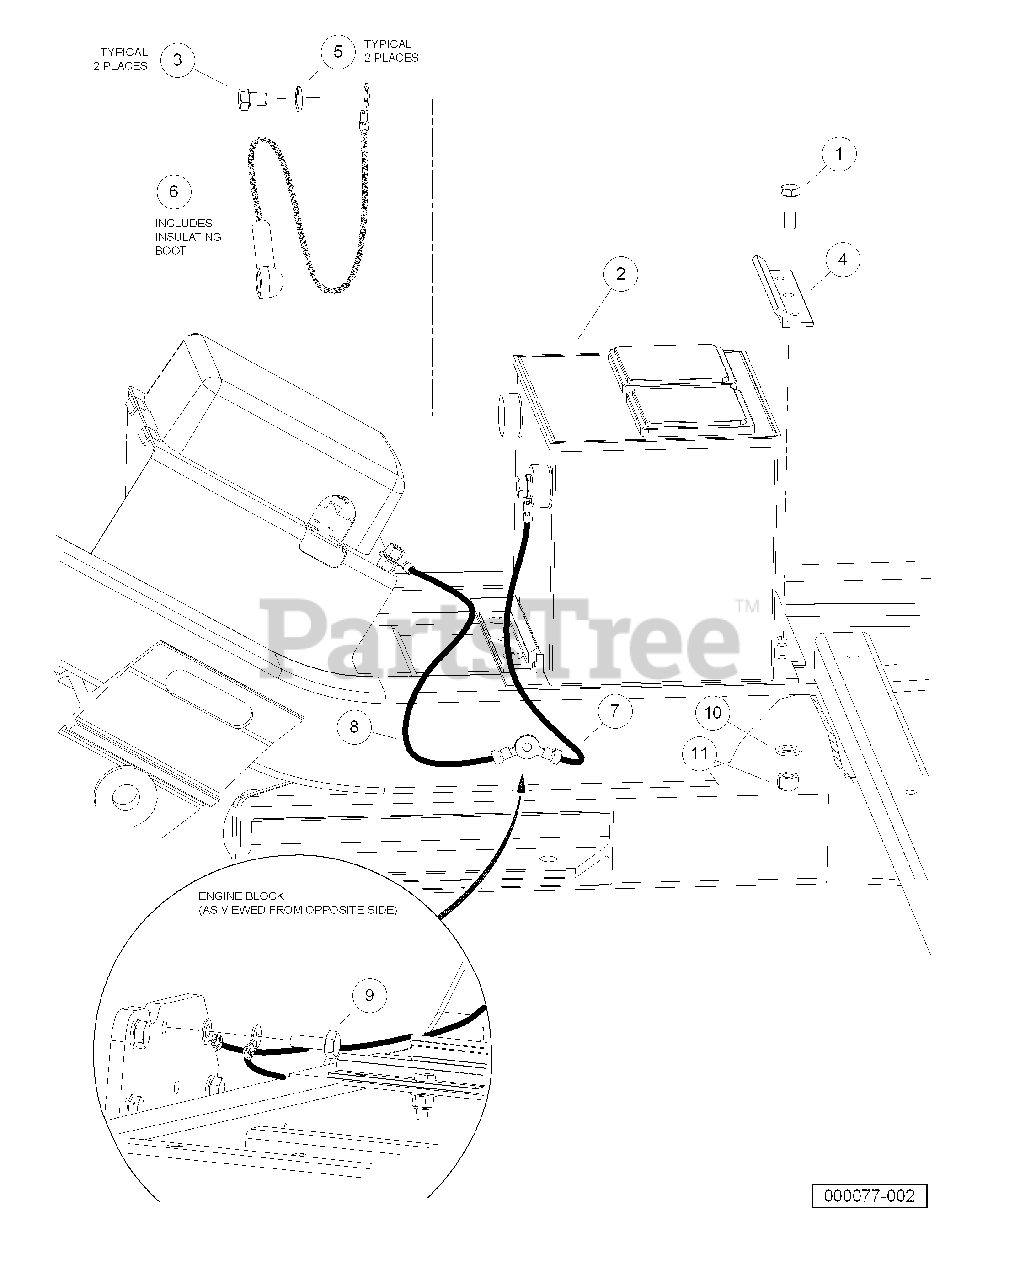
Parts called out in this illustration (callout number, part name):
1	Screw, 5/16-18 X 1.00 Hex Cap
2	Battery, 12-Volt
3	Screw, 3/8-16 X 0.50 Stainless Steel Hex-Head
4	Clamp, Battery
5	Lockwasher, 3/8 Stainless Stl
6	Asm, #6 Red Wire
7	Wire Asm, #6 Blk, Awd, 350
8	Wire Asm, #6 Blk, Awd, 325
9	Bolt, M10 X 1.25 X 25 Loctite
10	Washer, 5/16 Type A Flat
11	Locknut, 5/16-18 Nylon Insert
